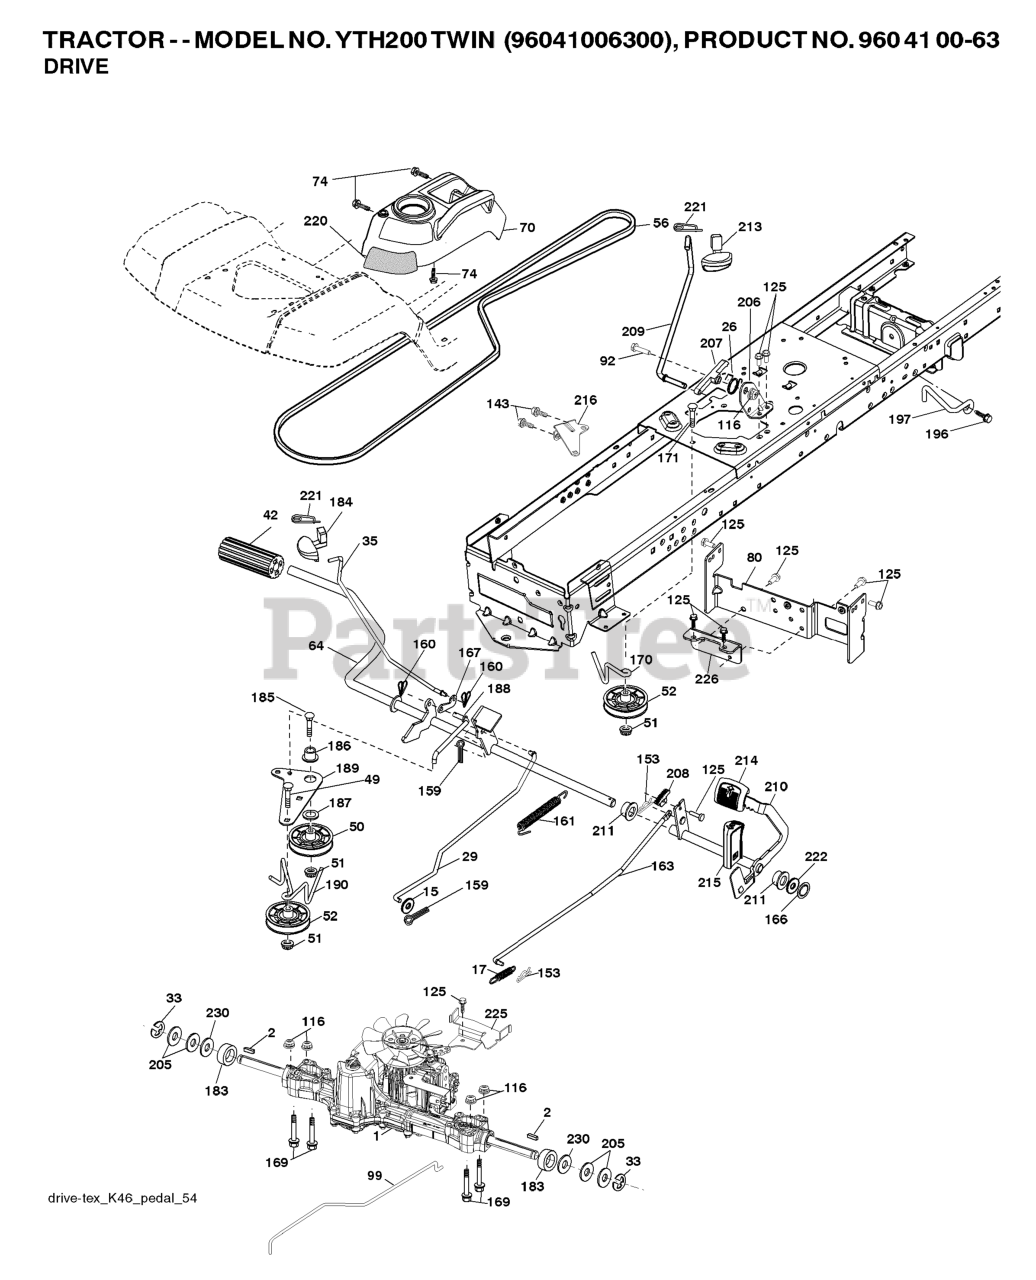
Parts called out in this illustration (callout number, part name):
2	SQUARE KEY
15	WASHER
17	SPRING.BRAKE.K46.GREEN
26	SPRING.RETURN.CRUISE
29	ROD.BRAKE.K46
35	ROD.BRAKE.PARKING.GT.H
42	PEDAL COVER T
50	IDLER.FLAT.910.OFFSET
51	NUT LOCK FLG 3/8-16 UNC
52	IDLER.V-GROOVE.910.OFFSET
56	V-BELT.MOWER.92.40.42/K46
64	SHAFT.ASM.PEDAL.BRK.CNTR
70	RP CONSOLE.ASM.PCH.W/TB
74	SCREW.HI-LO.CONSOLE
80	STRAP TORQUE
92	BOLT
99	ROD ASM BYPASS
116	NUT LOCK HEX FLANGE 5/16-18
125	SCREW
143	Screw 5/16-18 x 1/2 Hex, Self Tapping 5/16-18 x 1/2
153	RETAINER M
159	COTTER PIN
160	RETAINER CLIP
161	SPRING, RETURN LT
163	ROD.CONTROL.PEDAL.K46
166	NUT.PUSH.625.2006
167	LATCH.BRAKE.SPRING
169	BOLT HEX 5/16-18 GR 5
170	KEEPER.V-IDLER.CENTER.
183	SPACER AXLE
184	HANDLE.PARKG.BRK.HUSQ X667
186	SPACER.RETAINER
187	WASHER 12/32X2X10GA
188	RP.LINK.CLUTCH.GROUND.DRIVE
189	BELLCRANK.GROUND.DRIVE.TEX.
190	KEEPER.BELLCRANK.DRIVE
196	SCREW 3/8-16X1
197	LINK.CLUTCH.ANIT-ROTAT
206	BRKT.MOUNT.LATCH.CRUIS
207	LATCH.CONTROL.CRUISE
208	GEAR.SECTOR.CONTROL.CR
209	ROD.CONTROL.CRUISE.GT.
210	ROCKER.ASM.PEDAL.CONTR
211	BEARING.NYLON
213	KNOB.CONTROL.CRUSIE.HU
214	PEDAL.FORWARD.TEX.GT.4
215	PEDAL.REVERSE.TEX.GT.4
216	BRACKET.PULLEY.IDLER.W/TEX
220	REFLECTOR.RH.TEX GT
221	RETAINER.SPRING.CLIP.H
222	WASHER 21/32 X 1-1/4 X 10 GA.
225	KEEPER.BELT.TRANSAXLE.K46
226	BRACKET.MOUNT.TORQUE.K46.TLT
230	WASHER.HARDENED
